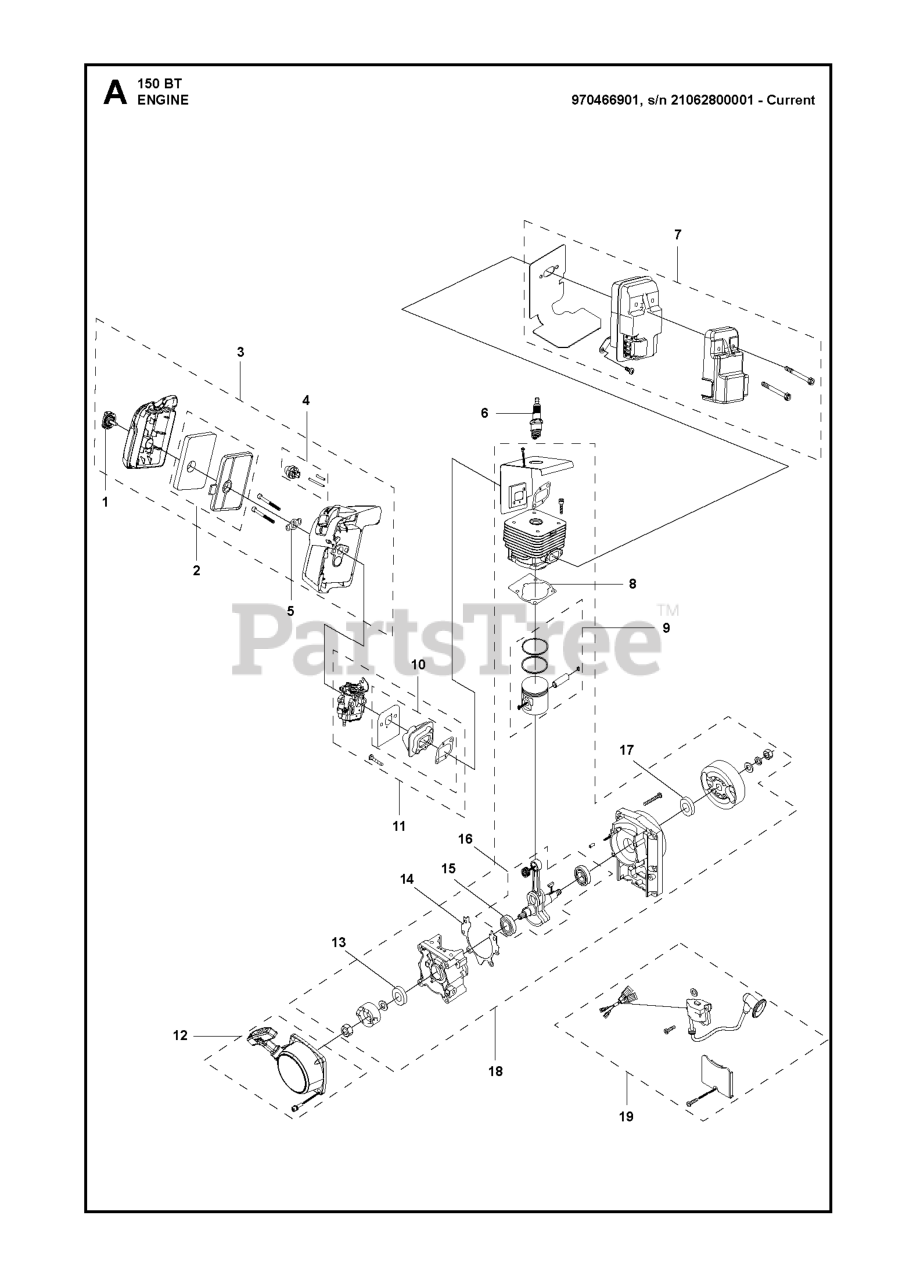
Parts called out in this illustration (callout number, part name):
1	KEEPER COVER KEEPER
2	AIR FILTER ASSY AIRBOX AND FIL
3	AIRBOX ASSY
4	PURGE PURGE BULB KIT
5	BAFFLE BAFFLE
6	SPARK PLUG M14X1.25 NGK BPMR7A
8	GASKET CYLINDER BASE GASKET
10	GASKET KIT GASKET KIT
11	CARBURETTOR
12	STARTER ASSY
16	CRANKSHAFT
18	Repair Kit
19	IGNITION COIL
